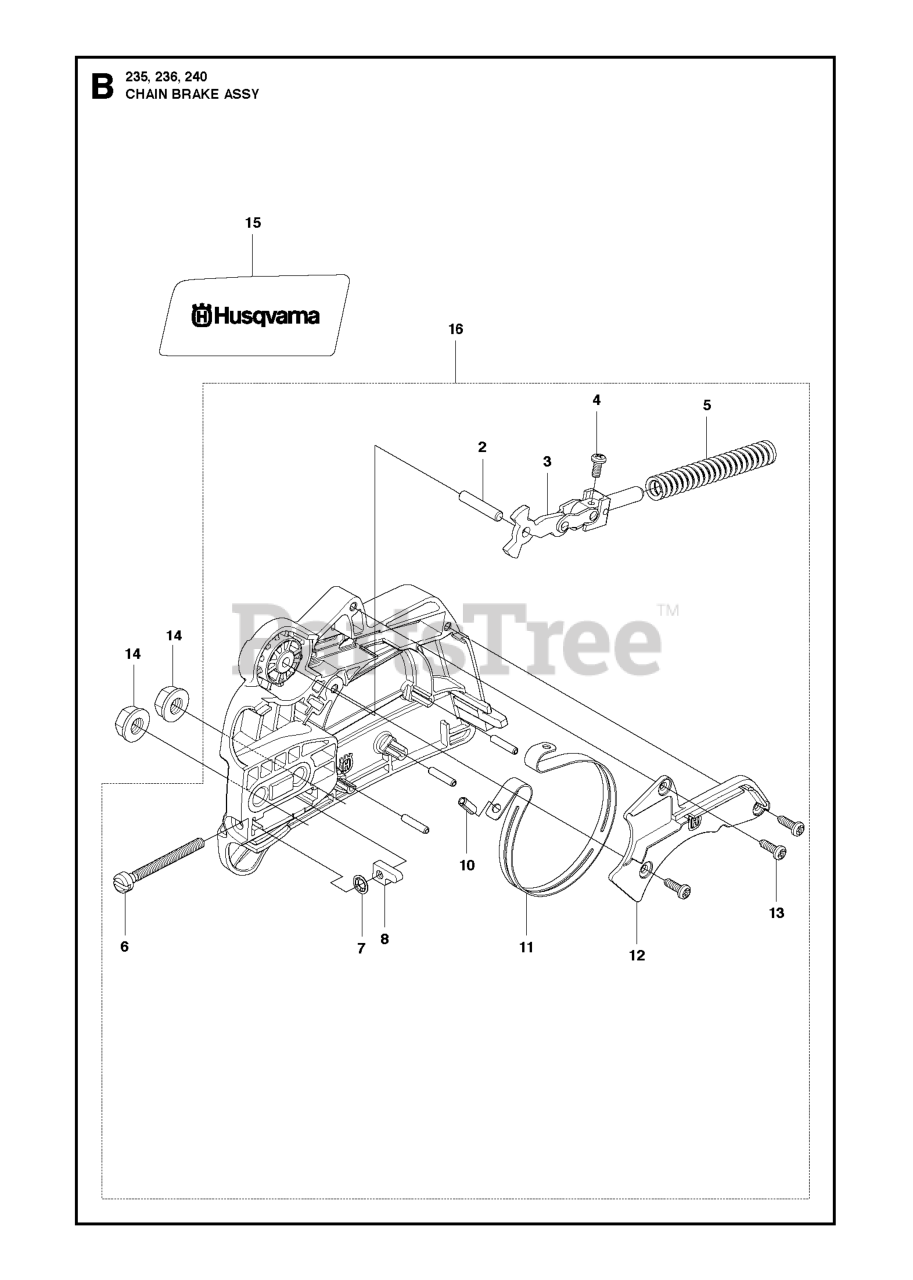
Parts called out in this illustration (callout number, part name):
3	FRONT LINK ASSY
4	SCREW
6	BAR ADJUSTING SCREW
8	ADJUST PIN,BAR 36/41
11	BRAKE BAND
12	COVER, BRAKE BAND
13	SCREW 6-19X.437
16	CHAIN BRAKE ASSY ORANGE
